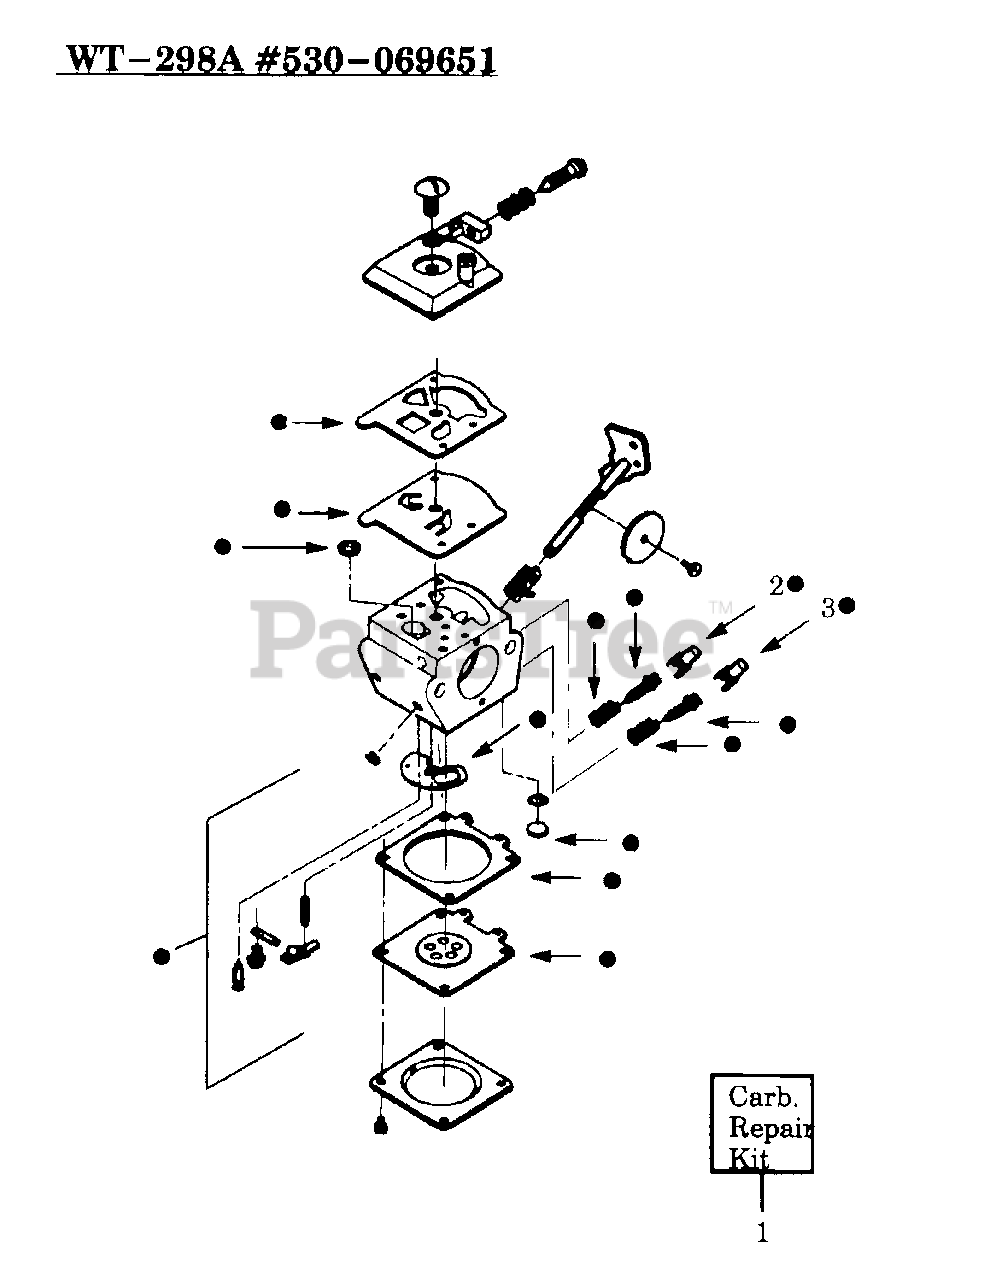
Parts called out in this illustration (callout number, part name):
1	Carburetor Repair Kit (DOT Indicates Contents on illus.)
2	Limiter Cap-Low
3	Limiter Cap-High
